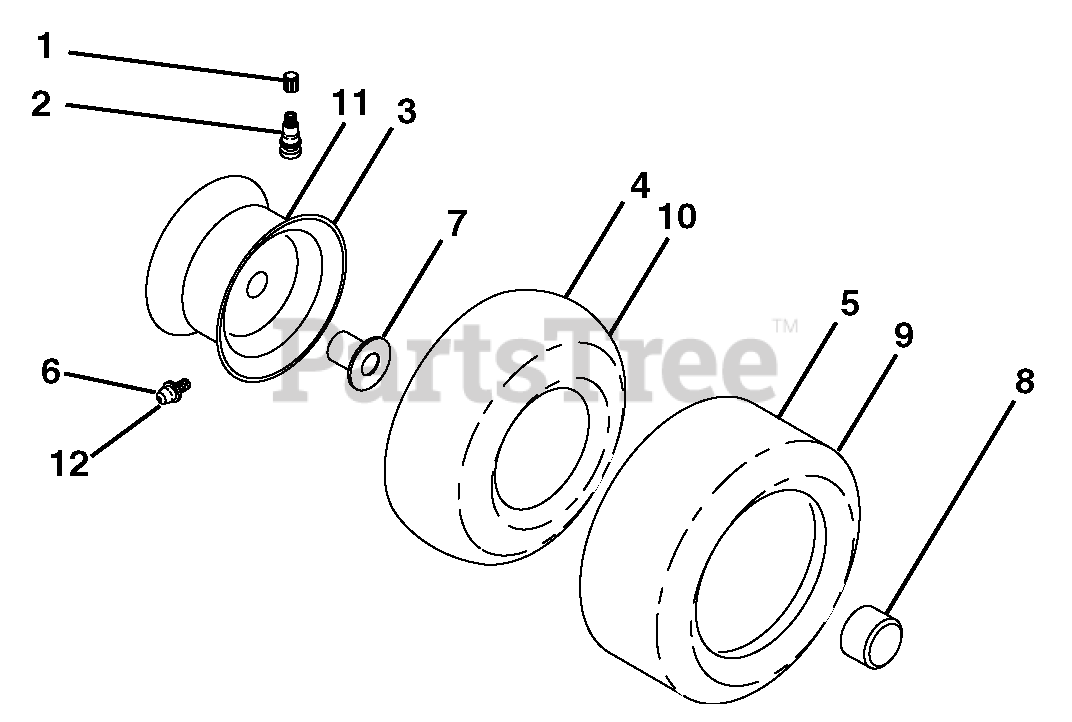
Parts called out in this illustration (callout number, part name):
2	VALVE STEM LT
3	RIM ASSEMBLY, FRONT
4	TUBE.16X6.5/7.5-8
5	TIRE HEAVY DUTY
6	FITTING LT.
7	BEARING.FLANGE
8	CAP, AXLE BLK
9	TIRE.22X9.50-12.TURF.SAVER.REA
10	TUBE.23X9.5-12
11	RIM.ASM.12".REAR.SILVER
12	FITTING, GREASE
12	TIRE SEALANT
